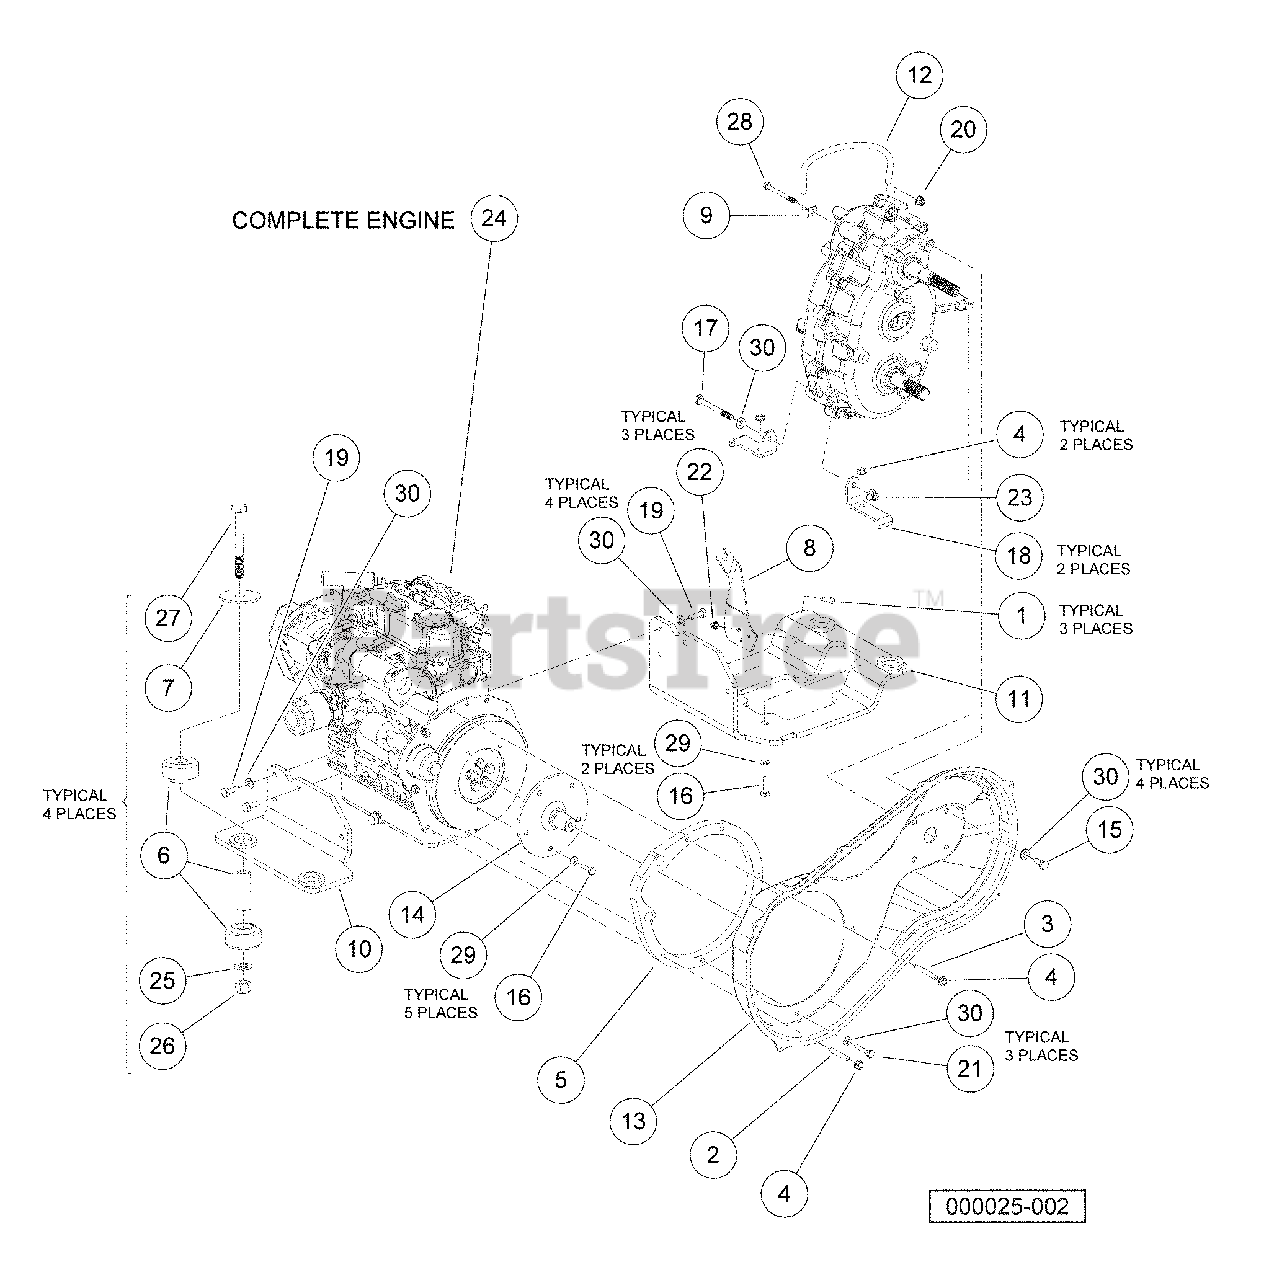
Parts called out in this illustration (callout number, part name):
1	Screw, M6-1.00 X 25mm Hex Cap
2	Stud, M8-1.25 X 50 mm Two-Ended
3	Stud, M8-1.25 X 60mm Two-Ended
4	Nut,m8,all Metal Lock
5	Spacer, Engine, Diesel
6	Isolator Ring and Bushing
7	Washer, Snubbing, Ring N Bush
8	Bracket, FNR Trans Cable
9	P-Clamp, Insulated .312 In
10	Plate, Engine Mounting, Weld, Left-Hand
11	Plate, Engine Mounting, Weld, Right-Hand
12	Hose, Vent, Transmission
13	Cover, CVT Inner, Diesel
14	Shaft, CVT Adapter
15	Bolt, M10 X 1.5 X 20 Loctite
16	Bolt, M8 X 1.25 X 25 Loctite
17	Bolt, M10 X 1.5 X 100 Loctite
18	Bracket, Transmission Mounting
19	Bolt, M10 X 1.25 X 25 Loctite
20	Lock Nut, Flg M8 X 1.25 Nylon
21	Bolt, M8 X 1.25 X 40 with Loctite
22	Nut Flg, M6 X 1.0 Nylon
23	Nut Flg M10 X 1.5 Nylon
24	Engine, Kubota, D722, with Closed Breather, 60a
25	Washer, M12 Hard
26	Locknut, M12x1.75 Nylon Insert
27	Bolt, M12 X 1.75 X 90
28	Bolt, M8 X 1.25 X 80
29	Washer, M8 Hard
30	Washer, M10 Hard
